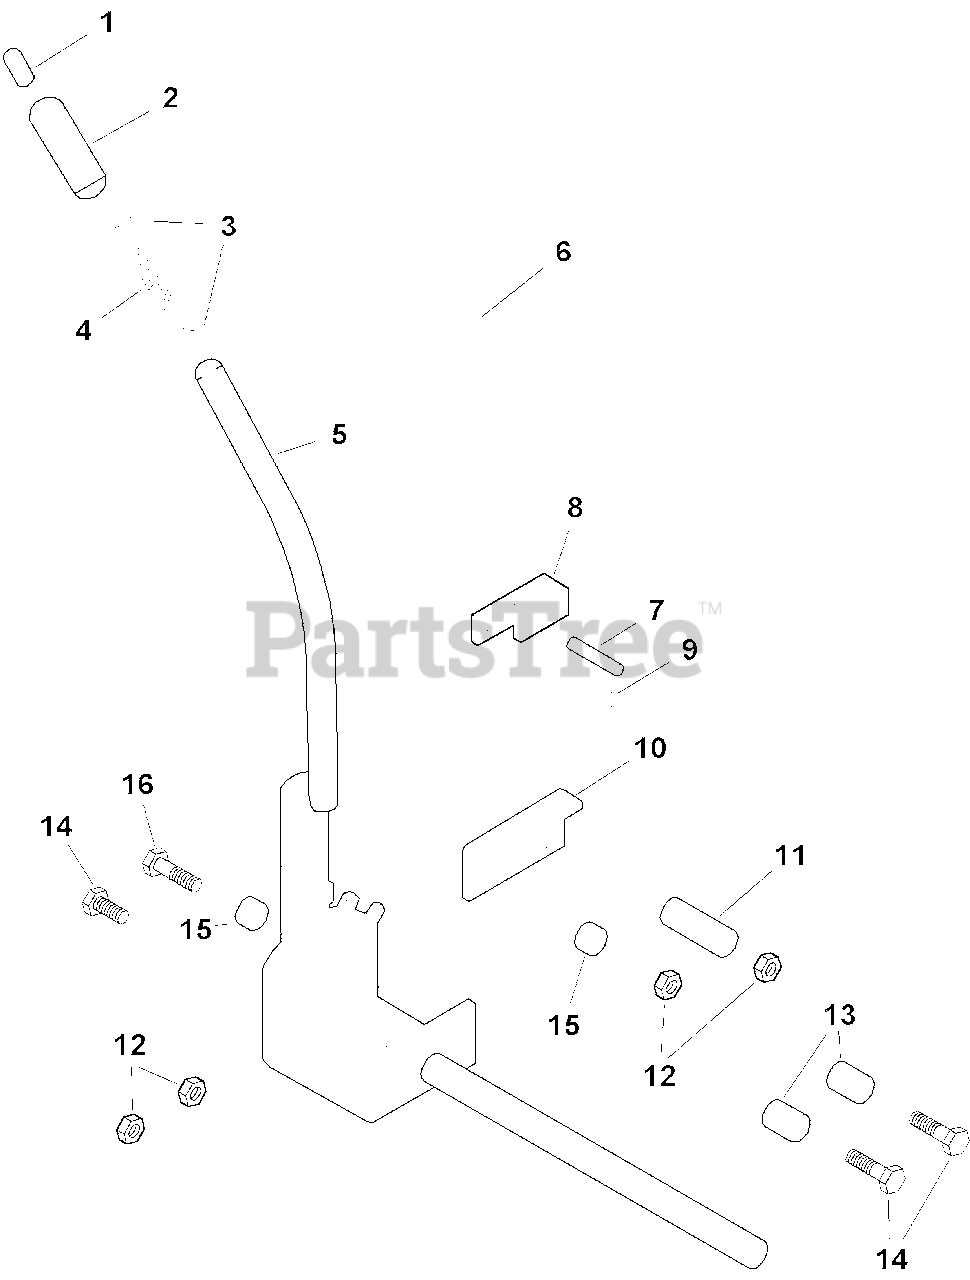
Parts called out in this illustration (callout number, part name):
2	GRIP, Black
3	WASHER
4	SPRING, Compression
5	QUADRANT & LEVER ASSEMBLY
7	ROLL PIN, 3/8 x 1
8	LATCH, Lift Lever
10	BRACKET
11	SPACER-0.39 IDX0.625O
12	NUT, ESNA, Hex Lock, 5/16-18
14	CAPSCREW, Hex Head, 5/16-18 x 1 1/4
16	CAPSCREW, Hex Head, 5/16-18 x 2-1/2
